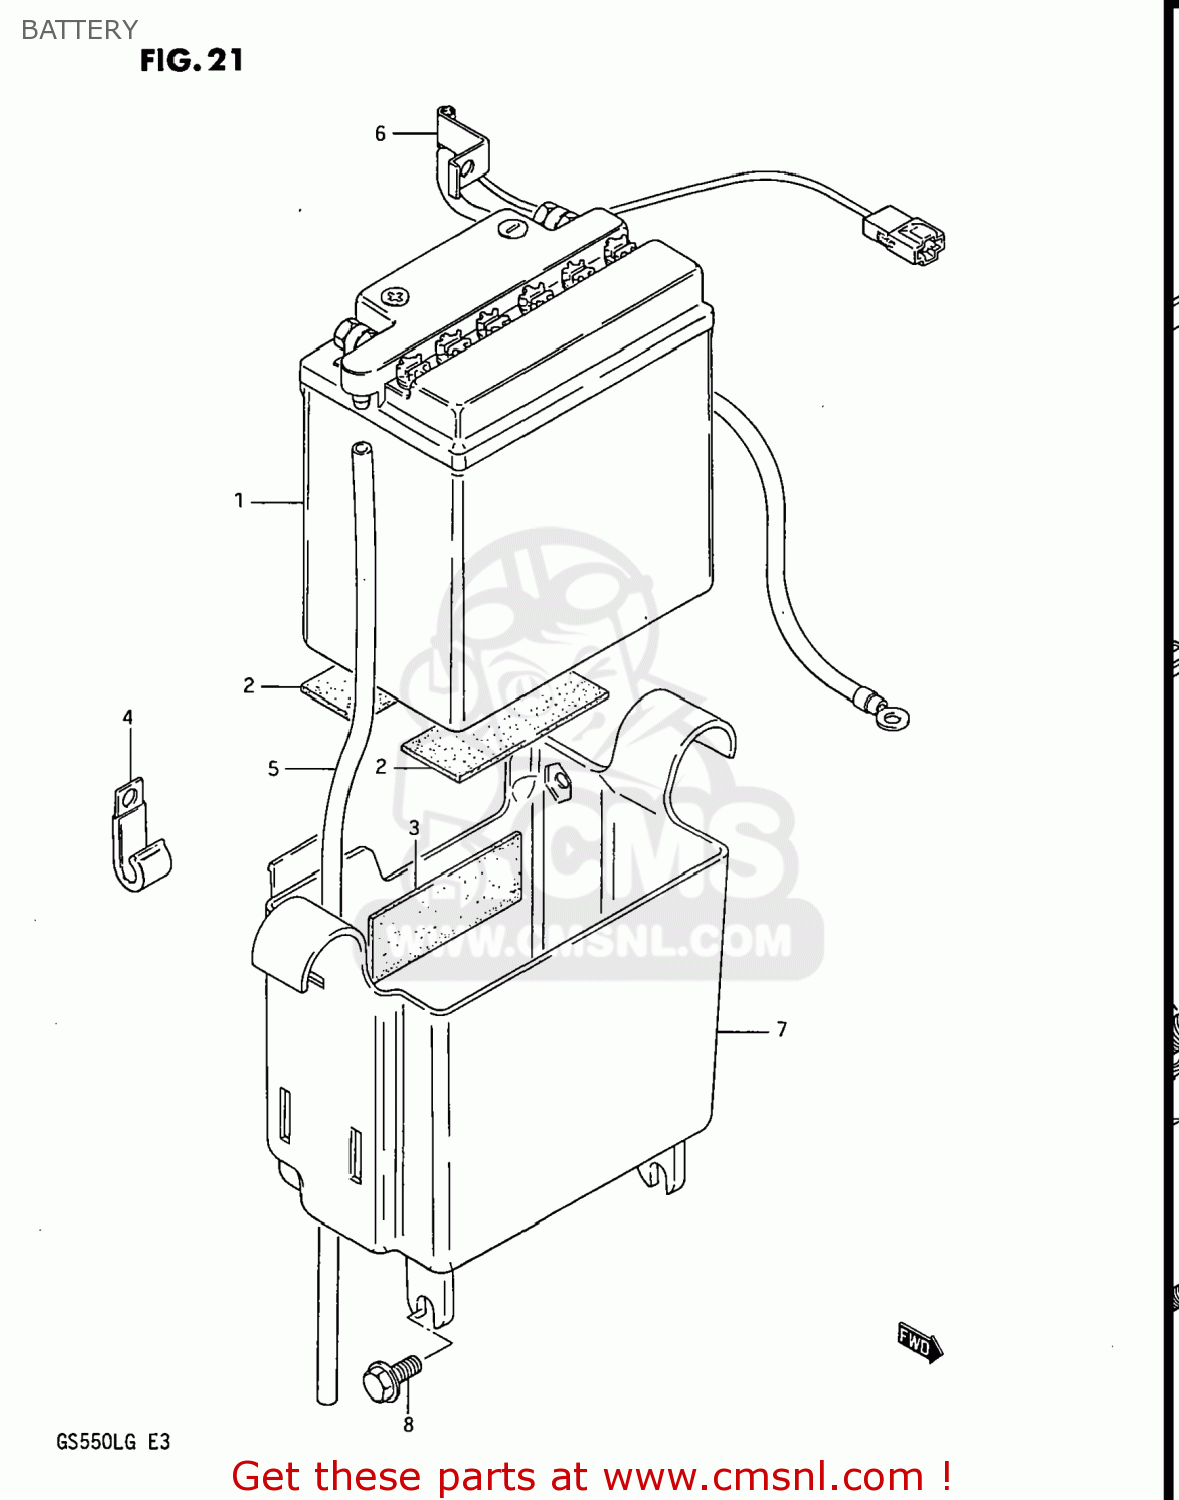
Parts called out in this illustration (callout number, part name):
1	BATTERY ASSEMBLY (12V)
2	PROTECTOR(30X80X2)
3	PROTECTOR,20X9
4	CLAMP
5	HOSE,BATTERY EXHAUST
6	CORD,BATTERY MINUS
7	HOLDER,BATTERY
8	SCREW
